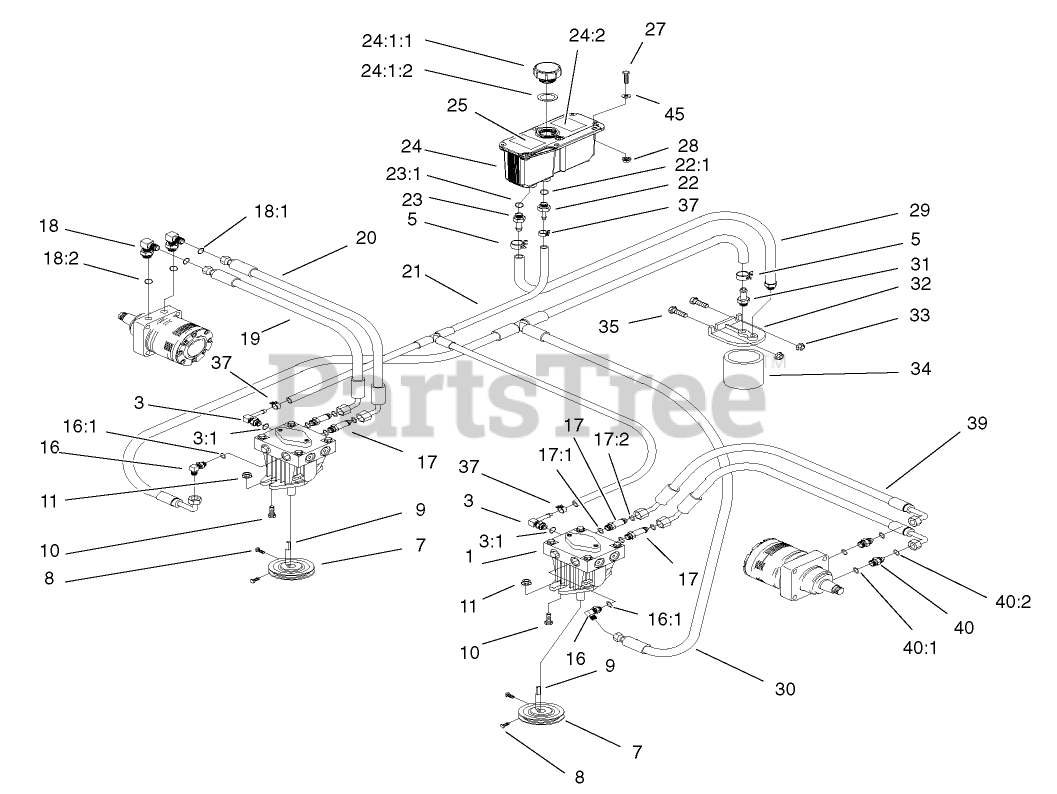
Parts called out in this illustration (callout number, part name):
1	PUMP-HYD
3	ELBOW-90 DEG
3:1	O-RING
5	Clamp-Hose
7	PULLEY
8	SCREW-SET
10	SCREW-HH
11	NUT-HHF, WHIZ
16	FITTING-ELBOW, 90 DEG
16:1	O-RING
17	ADAPTER-HYD, STRAIGHT
17:1	O-RING
17:2	O-Ring
18	FITTING-HYD, 90 DEG
18:1	O-Ring
18:2	O-RING
19	HOSE-FRONT
20	HOSE-REAR, RH
21	HYD Hose ASM
22	Adapter-Straight
22:1	O-RING
23	ADAPTER-STRAIGHT
23:1	O-RING
24	HYD Reservoir ASM
24:1	HYD Reservoir ASM
24:1:1	CAP-RESERVOIR, HYD
24:1:2	GASKET-CAP
24:2	DECAL-TANK, HYD
25	DECAL-EXHAUST
27	SCREW-HH
28	NUT-HF
29	HYD Hose ASM
30	HYD Hose ASM
31	Adapter-Straight
32	HEAD-FILTER
33	NUT-HF
34	FILTER-OIL, HYD
34	FILTER-OIL, HYD (WINTER)
35	SCREW-HH
37	Clamp-Hose
39	Hose-LH
40	Fitting-Straight
40:1	O-RING
40:2	O-Ring
45	WASHER-FLAT
